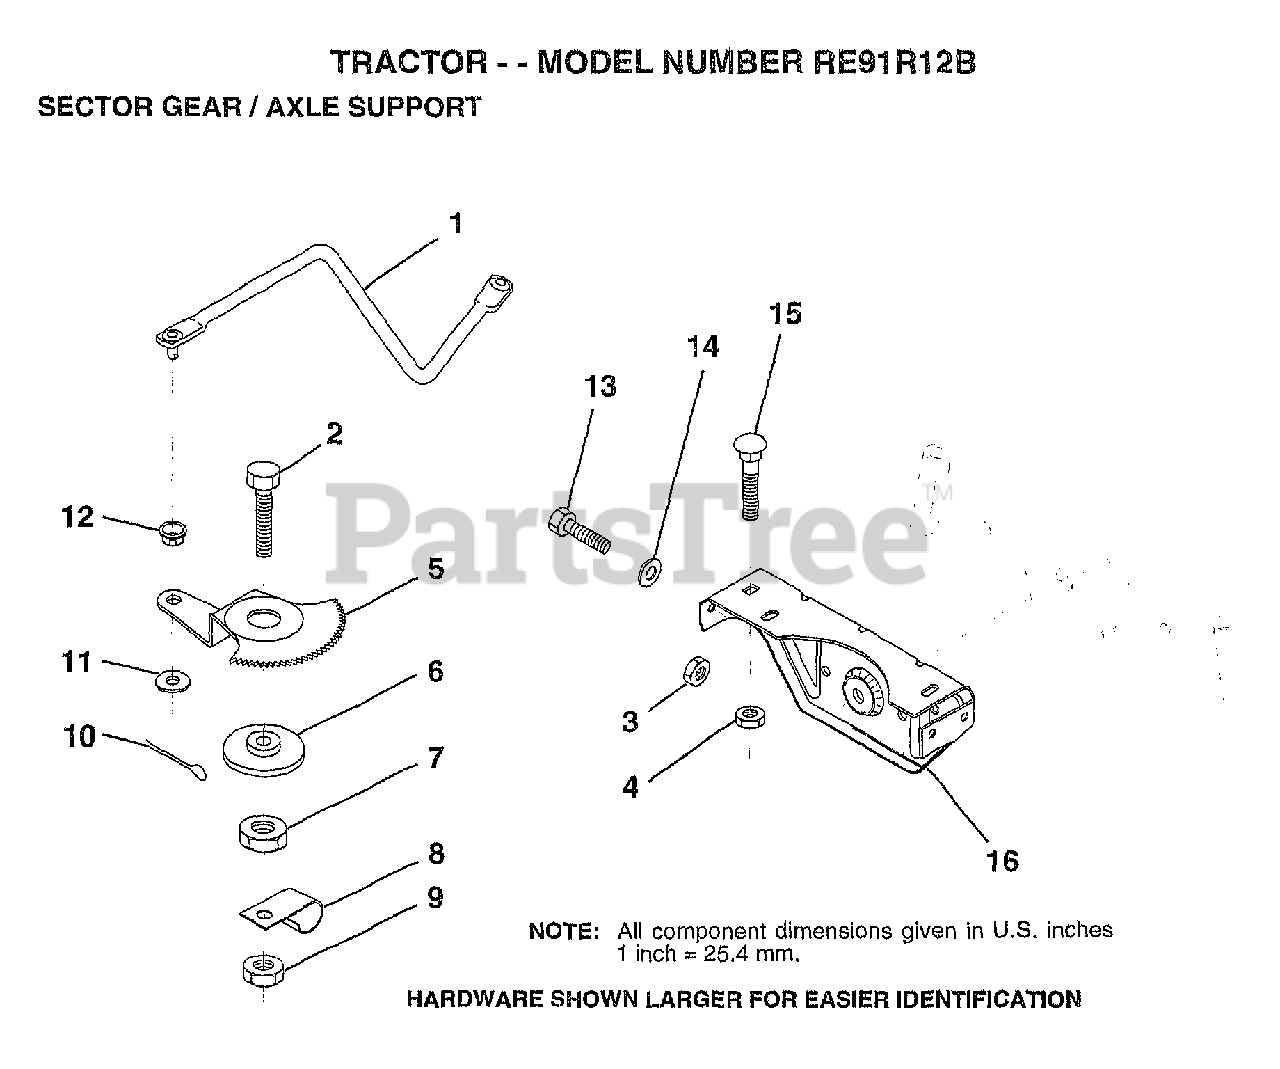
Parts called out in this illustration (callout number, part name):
1	DRAG LINK
2	"BOLT,HEX"
5	GEAR SECTOR
6	BUSHING
7	NUT
8	CLIP INSULATOR
9	NUT LTV
10	COTTER PIN
11	WASHER
12	BUSHING.DRAGLINK
13	BOLT
14	WASHER
15	BOLT
16	SUPT AXLE FRONT
